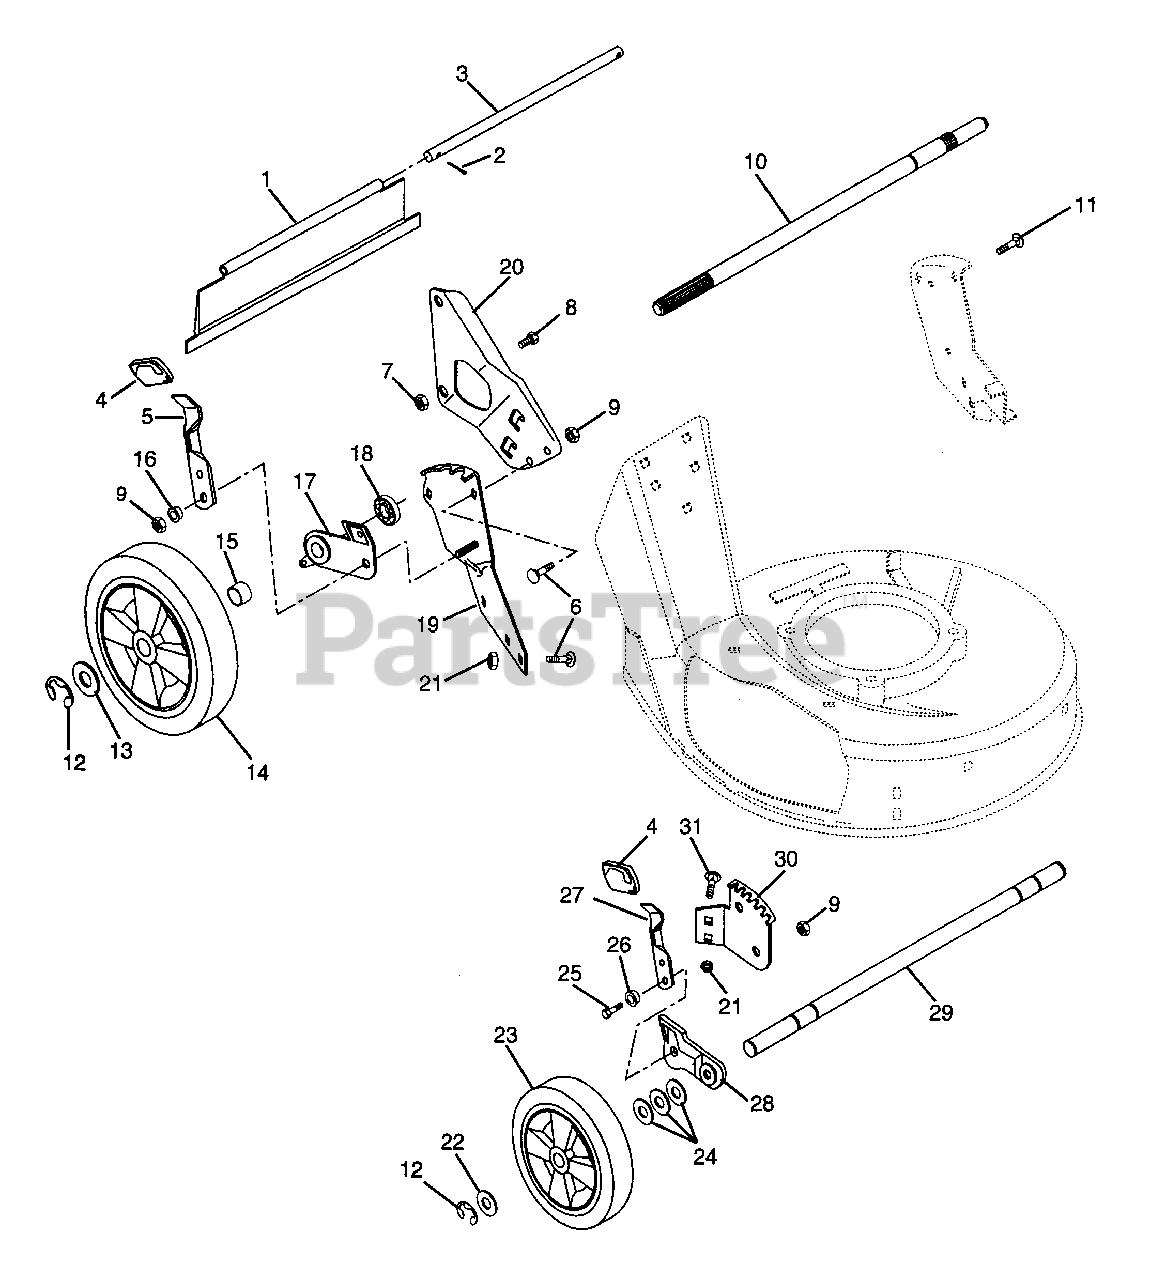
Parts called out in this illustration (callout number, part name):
1	REAR PROTECTIVE GUARD, PUSH
1	REAR PROTECTIVE GUARD, S.P.
2	@PIN-CTR .06X.50 EXTPRSQCT YWZ
3	ROD
5	HEIGHT ADJUSTMENT LEVER
6	@BLT-RHDSSQNK .31-18X.62 G5YZ
7	@NUT-LK-CTR .38-16 YWZC
8	HANDLEBAR STUD
9	@NUT-LK-CTR .31-18 YWZC
10	REAR AXLE,5/8 DIA
10	REAR AXLE-PUSH MOWER MM
10	REAR AXLE-PUSH MOWER
11	BLT-RDHDSQNK .31-18X1.0 SHTYZ
12	RG-RTNG-EXT .500X.042 (E)
14	LH WHEEL
14	RH WHEEL
14	TIRE 10X1.75
14	10 1/2 TIRE SKIN
15	SPACER TUBE,PUSH LH
15	SPACER TUBE PUSH RH
15	SPACER TUBE, SELF PROPEL
16	BSHG-FLG .32X.500X.344X.880
17	REAR BRACKET & BEARING ASSEMBL
17	REAR BRACKET&BEARING ASSY COMM
17	R.H. REAR ADJUSTOR BRACKET
17	L.H. REAR ADJUSTOR BRACKET
17	REAR ADJUSTMENT BRACKET L.H.
17	REAR BRACKET & BEARING ASSY RH
18	BRG-BALL .625X1.383X.50
19	QUADRANT, REAR - L.H.
19	REAR QUADRANT, R.H.
20	RH HANDLEBAR MTG. BRKT.
20	RH HANDLEBAR MOUNT WELDMENT
20	LH HANDLEBAR MTG. BRKT.
20	LH HANDLEBAR MOUNT BRKT WELDM
21	@NUT-SPNLK-FLG .312-18 YWZC
22	WSHR-FL-STL .505X.880X.072 YWZ
23	WHEEL
23	TIRE 7X1.50
24	WSHR-FL-STL .520X.827X.062 YZ
25	@BLT-HEX .31-18X1.00 GR5 YWZC
26	BSHG-FLG .32X.500X.344X.880
27	FRONT HEIGHT ADJUSTMENT LEVER
28	LEFT ADJUSTOR BRACKET ASSEMBLY
28	RIGHT ADJUSTOR BRACKET ASSEMBL
28	RH ADJUSTER BRACKET
28	LH ADJUSTER BRACKET
29	FRONT AXLE
30	FRONT QUADRANT, L.H.
30	FRONT QUADRANT, R.H.
31	@BLT-RDHDSQNK .31-18X.50 G5YZ
